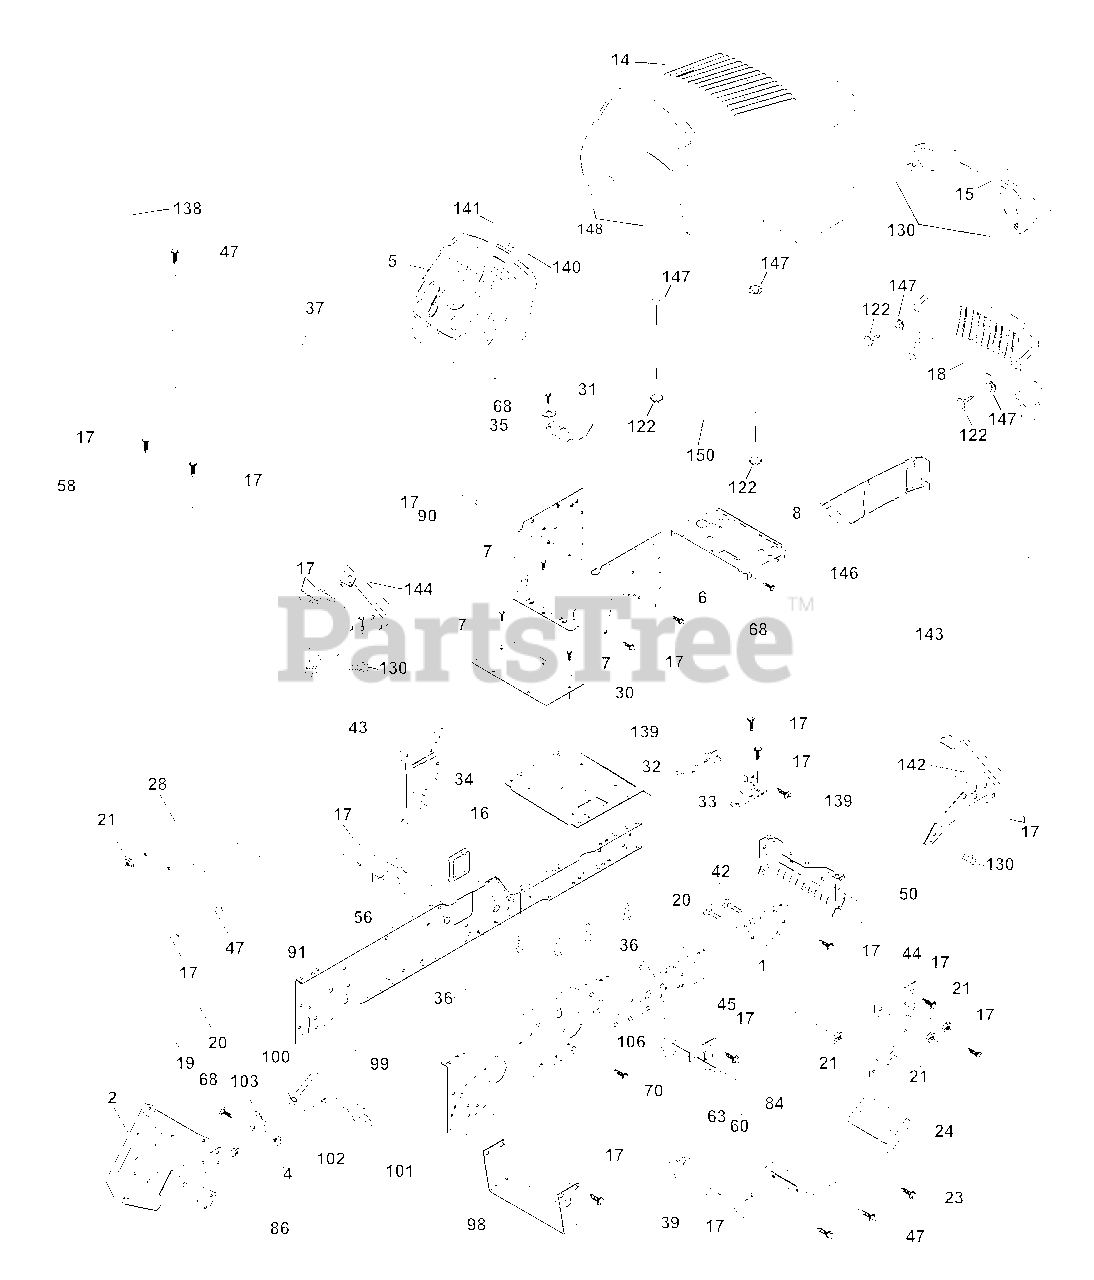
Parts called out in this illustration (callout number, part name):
1	Rail, Frame RH
2	Drawbar, Gt
4	Nut, Lock Hex 7/16 Unc
5	Dash, Plastic
6	Dash, 1PCS, Lower
7	Screw, Thd Cut 1/4-20 x 1/2
8	Support, Battery
14	Hood Asm., Pnt
15	Lens, Headlight Bar
16	Cover, Access
17	Screw, 3/8-16 x 3/4
18	Grille
19	Washer 13/32 x 13/16 x 12 Ga.
20	Bolt, Fin Hex 3/8-16 x 1
21	Nut, Crownlock 3/8-16
23	Screw 3/8-16 x 1-1/2
24	Footrest, RH
28	Footrest, LH
31	Bracket Supt 1-pc Vgt Steering
32	Bracket, Frame Pivot Lh
33	Bracket, Frame Pivot Rh
34	Plate Asm Engine Chassis
35	Washer 11/32 x 11/16 x 16 Ga.
36	Screw 5/16-18 x 3/4
37	Fender, Pnt.
39	Bracket, Axle Front
42	Bolt Rdhd Sqnk 3/8-16 Unc x 1
43	Bracket, Spnsn Front Lh
44	Bracket, Spnsn Front Rh
45	Bracket Asm., Susp Chassis Rh
47	Screw Thdrol 3/8-16 x 1/2
50	Bracket, Chassis Front
56	Bracket Asm., Susp Chassis Lh
58	Bracket Asm., Fender
60	Screw 3/8-16 x 1-1/4
63	Washer 13/32 x 1 x 14 Ga.
68	Screw, 5/16-18 x 1/2
70	Guide, Belt Mid Span
84	Stop, Over Center Mower
86	Bolt, Fin Hex 7/16-14 Unc x 1
90	Washer, Lock External Tooth 3/8
91	Rail, Frame Lh
98	Bracket Chassis Skid
99	Rod Asm. Bypass
100	Cap By Pass Rod
101	Screw Thdrol. 3/8-16 x 1-3/4
102	Retainer Spring 1"
103	Bracket Lock Bypass
106	Screw Thdrol Hex Head Zinc
122	Screw Hex WSHD 8-18 x 7/8
130	Screw Hw Hd Hi-Lo #13-16 x 3/4
138	Cupholder
139	Bolt Shoulder 5/16-18
140	Magnet Stealth
141	Striker Plate
142	Bracket Dash Stealth RH
143	Skirt Grille RH
144	Bracket Dash Stealth LH
146	Skirt Grille LH
147	Fastener Pal
148	Extrusion Bumper
150	Duct Heat Hood
